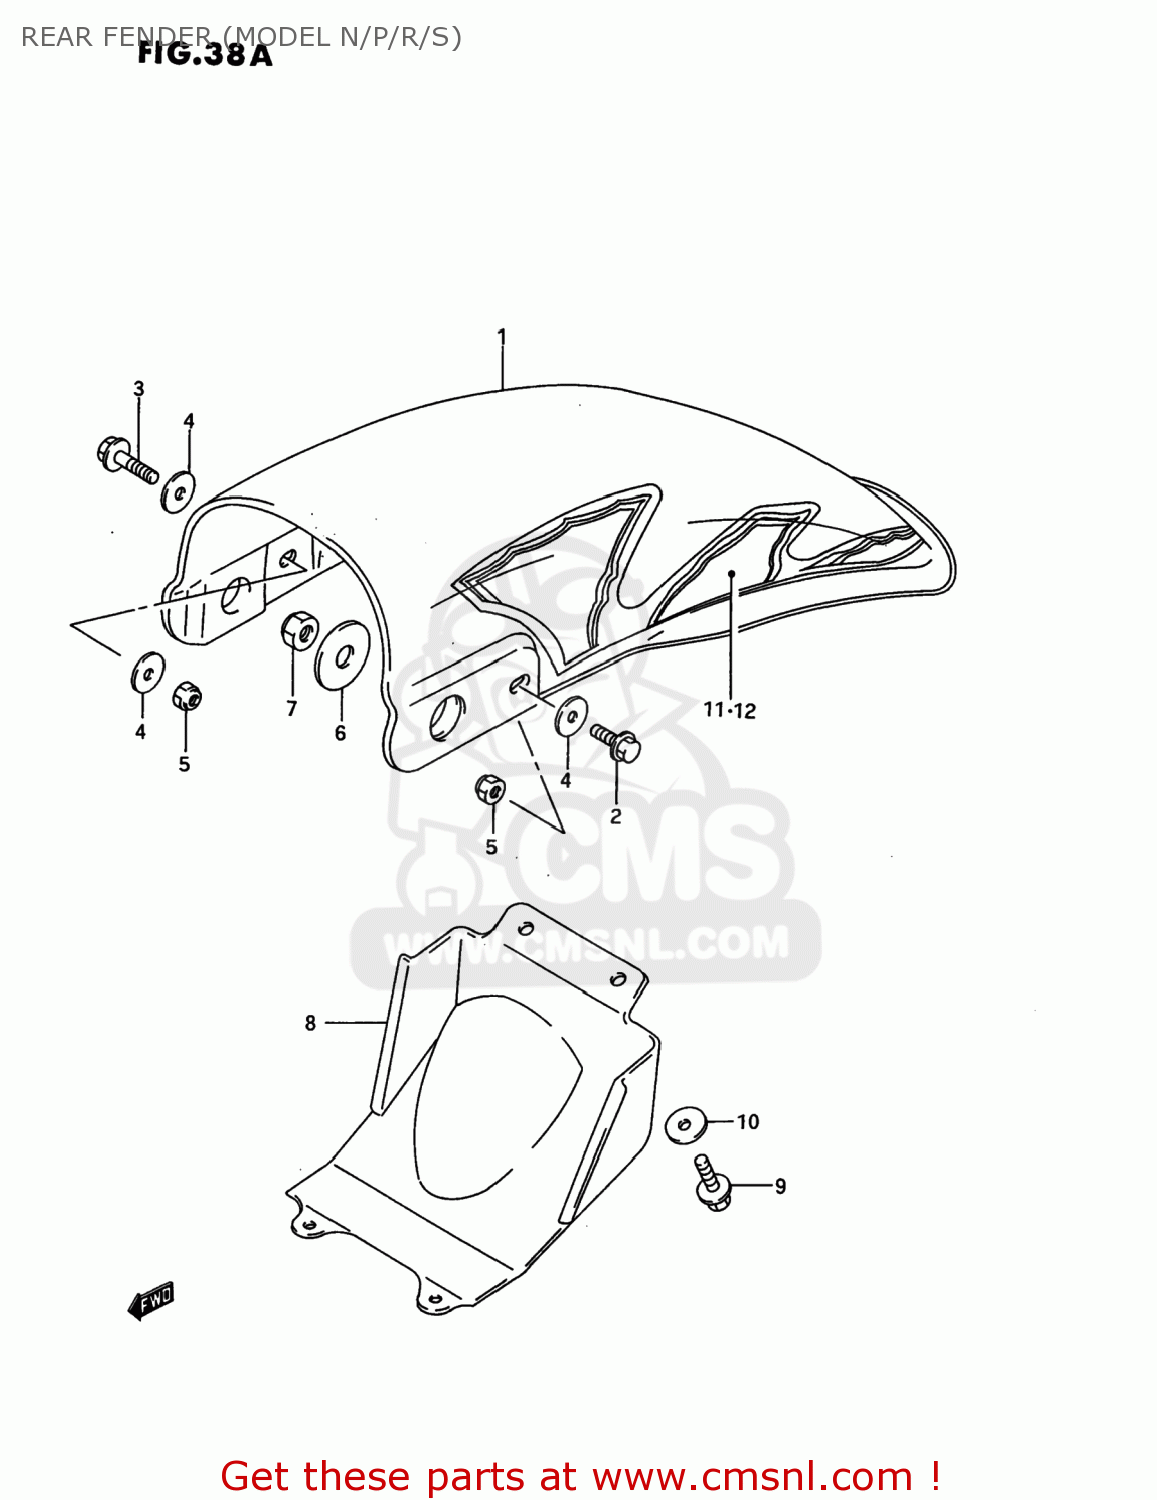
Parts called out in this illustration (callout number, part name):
1	FENDER,RR
2	BOLT
3	BOLT
4	WASHER(6.5X20X1.6)
5	NUT
6	WASHER (10.5X30X2.3)
7	NUT
8	MUDGUARD,RR FENDER FR
9	BOLT
10	WASHER
11	EMBLEM,REAR FENDER,RIGHT
12	EMBLEM,REAR FENDER,LEFT
